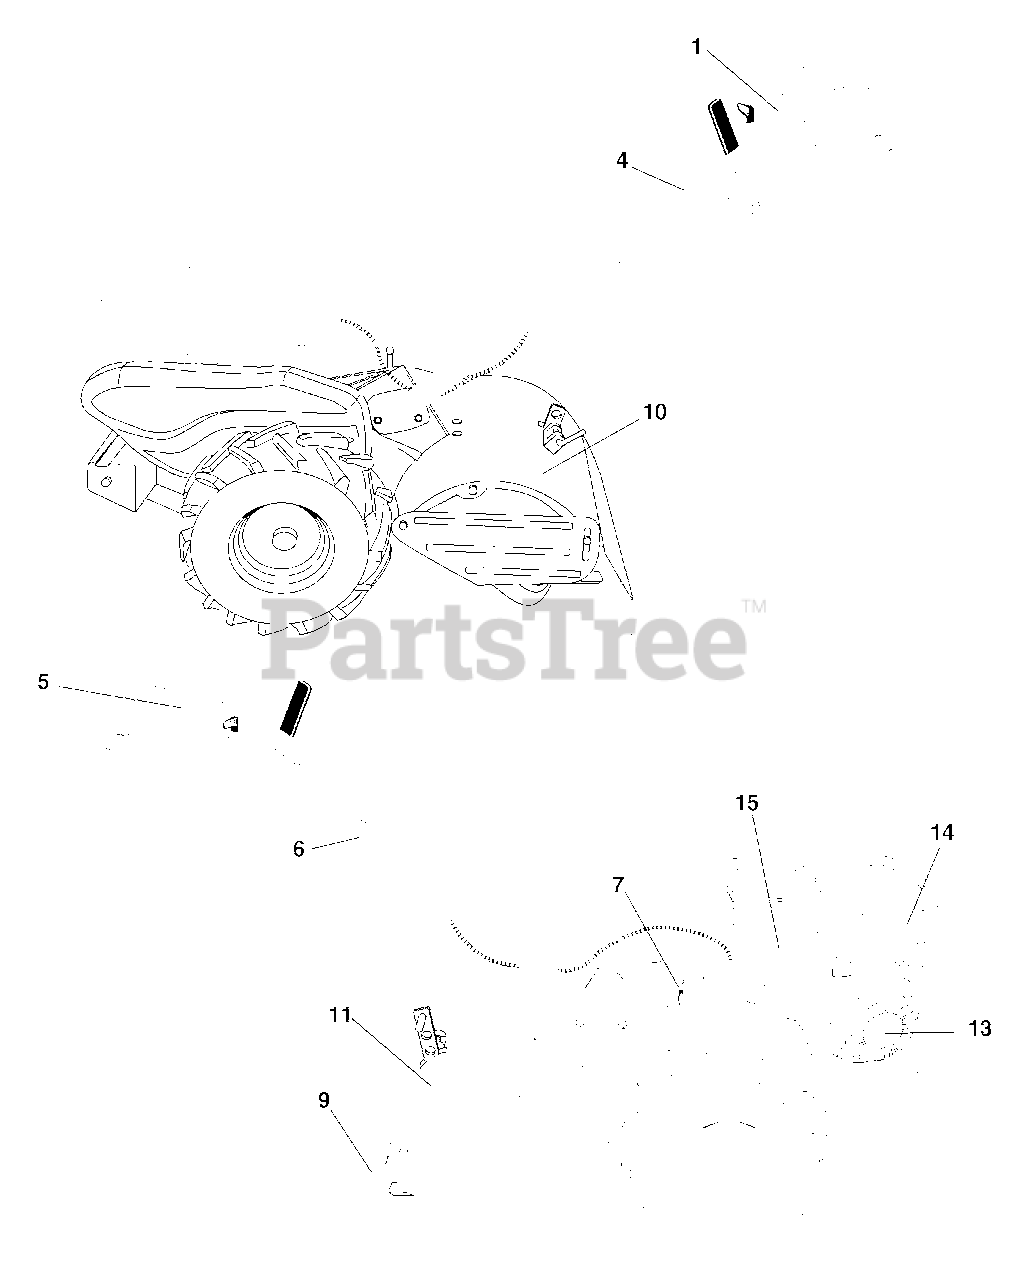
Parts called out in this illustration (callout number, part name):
1	Decal, Service CNTRL PNL
3	Decal, Blt Guard
4	Decal, Control Panel
5	Decal, Caution, Drive Control
6	Decal, Hand Placement
7	Decal, Shift Indicator
8	Decal, Tine, Shield, Counter Rotating Tines
9	Decal, Warning, Rotating Tines
10	Decal, Tine
11	Decal, Tine, Shield, Warning Dom
13	Decal, Rewind
14	Decal, Engine
15	Decal, Intek
